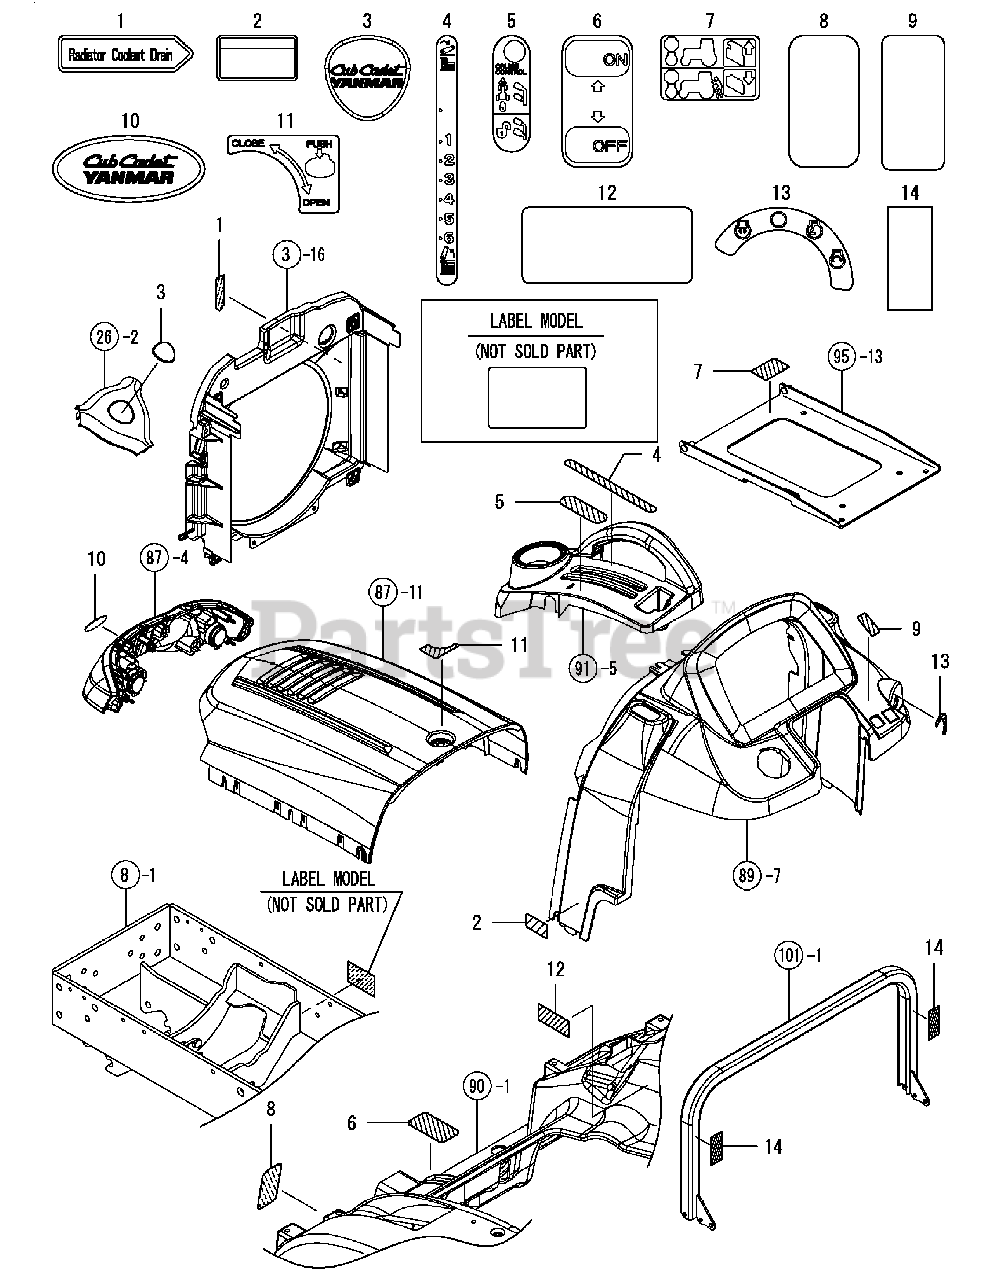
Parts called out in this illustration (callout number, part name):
2	LABEL, FUEL OIL
3	LABEL, STEERING WHEEL
4	LABEL POSITION
5	LABEL LEVER GUIDE L
6	LABEL, LEVER 4WD
7	LABEL, LEVER VALVE
8	LABEL, DIFFLOCK
9	LABEL,ACCELERAT. LVR.
10	LABEL CENTER LOGO
11	LABEL HOOD OPEN
13	LABEL, START SWITCH
14	TAPE, REFLECTION
